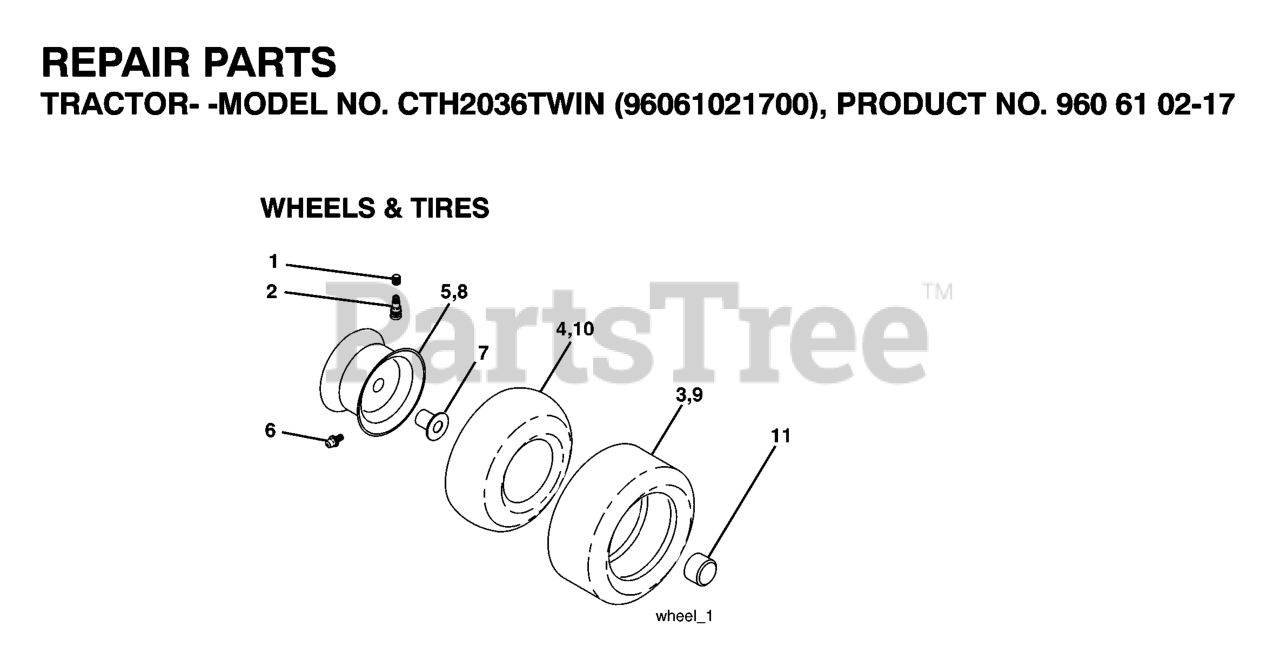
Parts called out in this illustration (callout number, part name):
2	VALVE STEM LT
3	TIRE HEAVY DUTY
4	TUBE.5.3/4.5/6
5	RIM ASM 6" FRONT SILVER
6	FITTING LT
7	BEARING T
8	RIM ASM 8" REAR SILVER
9	TIRE.TS.20X10-8
10	TUBE
11	CAP, AXLE BLK
